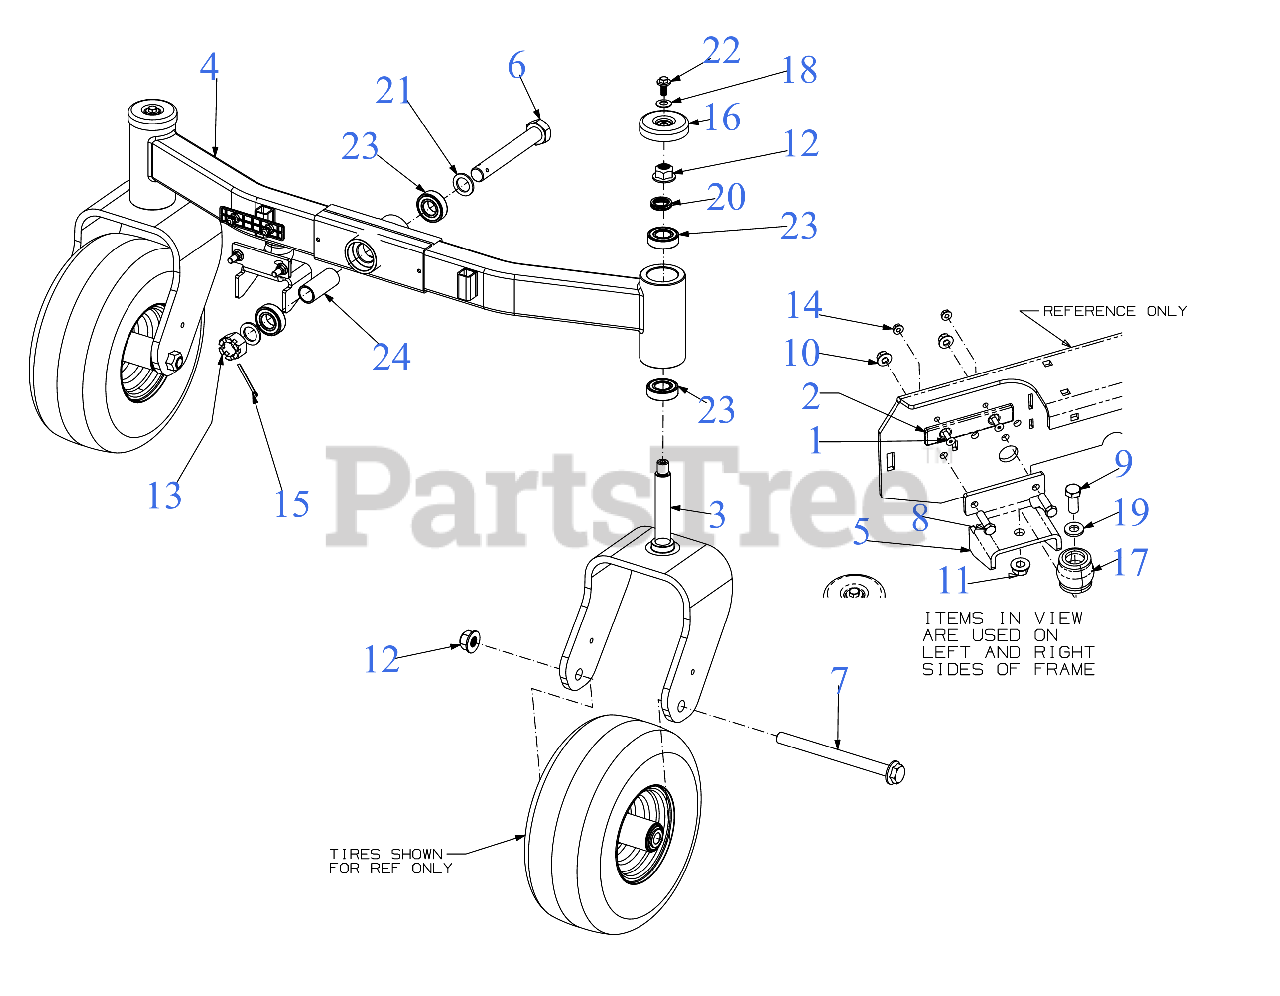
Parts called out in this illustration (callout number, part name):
1	SCREW-FLAT HEAD CA
2	PLATE-LIFT WEAR
6	HEX HEAD SCREW (1-14 x 7 GR5)
7	SCREW 3/4-16 x 9.00 GR5
8	SCREW 3/8-16 x 1.25 GR5
9	SCREW 1/2-13 x 1.25 GR5
12	FLANGE LOCK NUT 3/4-16 TOP LOCK
13	CASTLE NUT 1.0-14 GR5
14	LOCK NUT 1/4
15	COTTER PIN
16	AXLE CAP 3"
17	AXIAL BUMPER
18	BELL WASHER
19	FLAT WASHER
20	WAVE WASHER
21	FLAT WASHER 1.005 x 1.570 x 0.125
23	BALL BEARING (1.0 x 52 x 15)
24	SPACER 1.00 x 1.25 x 2.99
